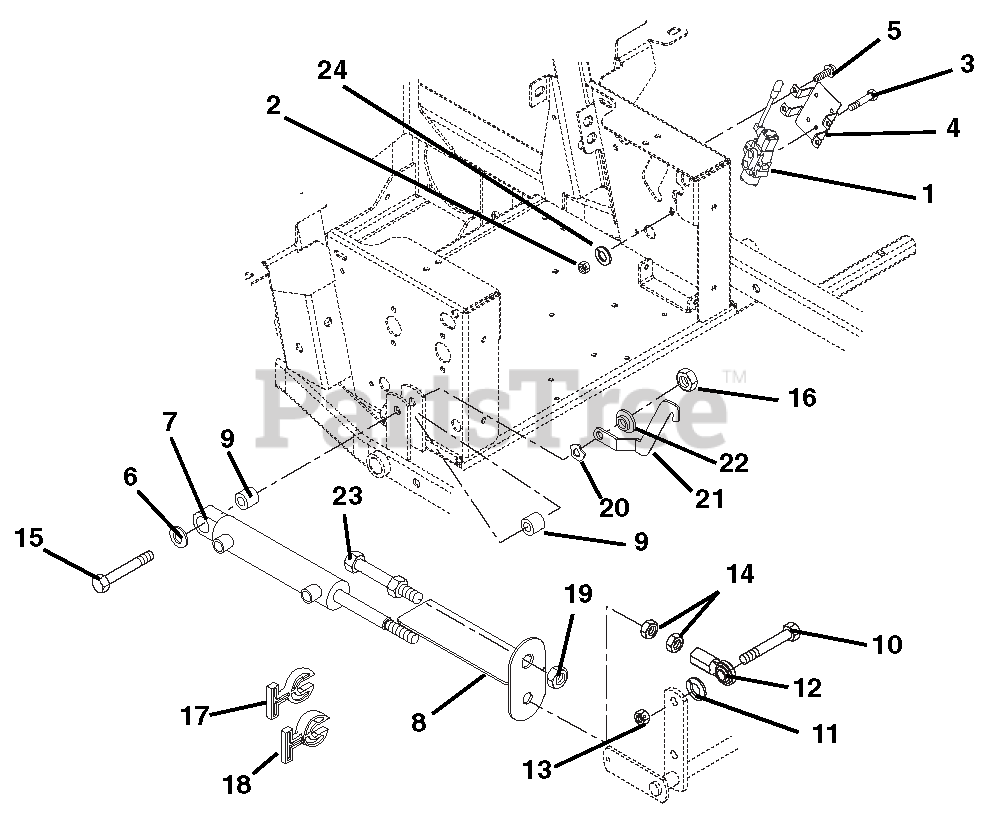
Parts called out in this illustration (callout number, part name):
1	VALVE - HYDRAULIC LIFT
2	@NUT-LK-CTR .31-18 YWZC
3	@BLT-HEX .31-18X2.00 GR5 YWZC
4	BRACKET - VALVE MOUNTING
5	@SCR-TAP .38-16X.50 HWH TR YWZ
6	WSHR-FL-STL .515X1.625X.250 YZ
7	CYLINDER, LIFT
8	CUT INDICATOR/GUARD - BLACK
9	BUSHING, .516X1.000X1.050 LG
10	BLT-HEX .62-11X2.25 YWZC GR8
11	@WSHR-LK .62X.156 REG YWZC
12	ROD END, 5/8 RH - FEMALE
13	@NUT-LK-CTR .62-11 YWZC
14	NUT-JAM .625-18 YWZC
15	@BLT-HEX .50-13X3.75 GR5 YWZC
16	@NUT-LK-TOP-FLG .50-13 YWZC
17	STOP, CYLINDER .34 THK
18	STOP, CYLINDER .680 THK
19	NUT-JAM .75-16 YWZC
20	WASHER-WAVE .760X1.120X.080
21	LATCH, FOOTBOARD HOOK
22	BSHG-FLG .515X.750X.285X1.120
24	@WSHR-LK .31X.078 REG YWZC
